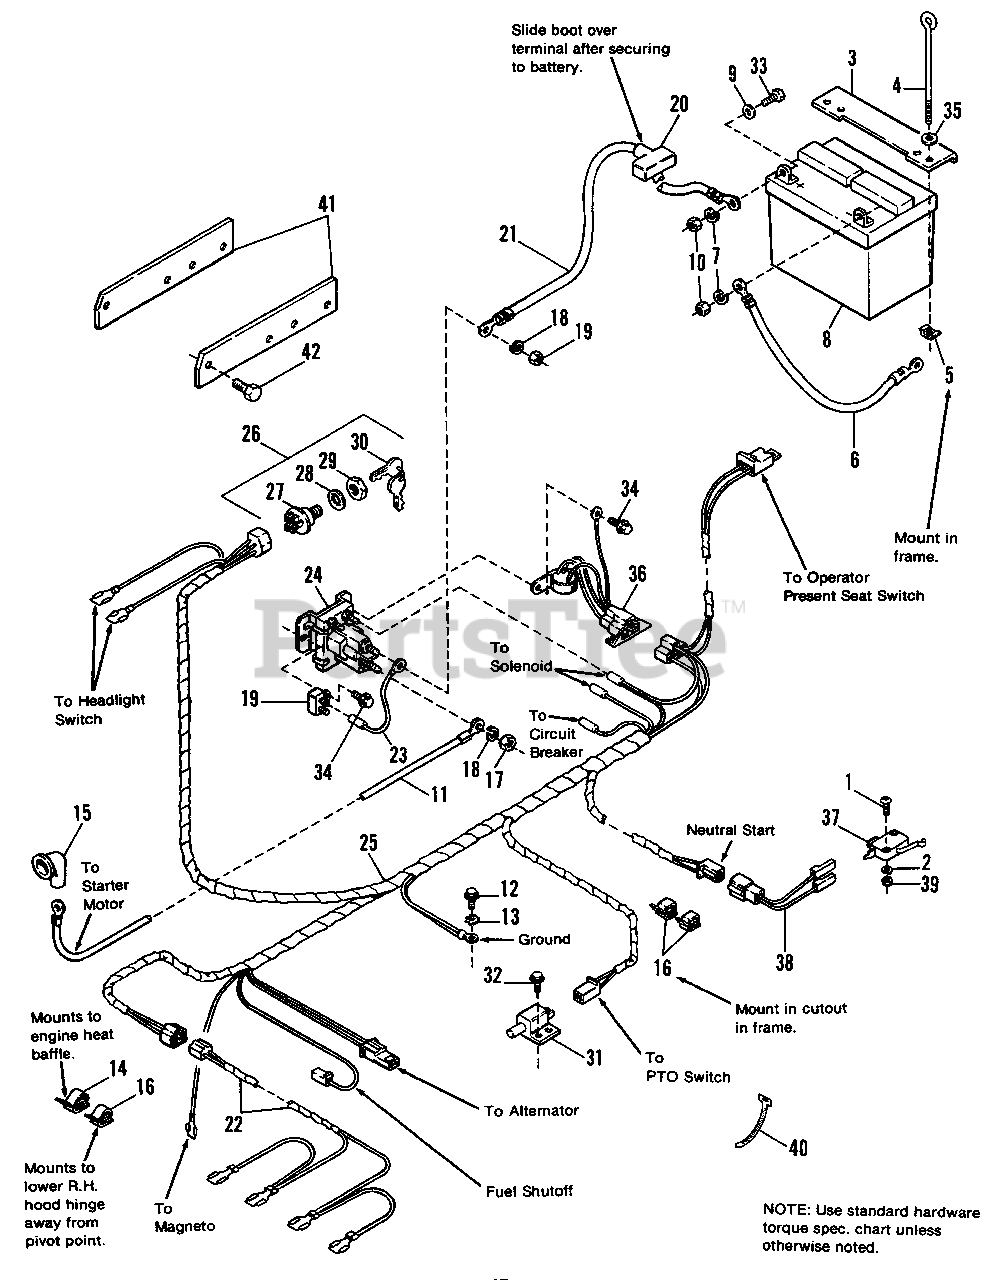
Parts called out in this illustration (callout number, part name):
1	SCREW, Phillips, #5-40 x 3/4
2	LOCKWASHERS, #5
3	HOLD DOWN, Battery
4	HOLD DOWN, Battery, Thrd.
5	NUT, Retainer, 1/4-20
7	LOCKWASHER, 1/4
8	BATTERY SERVICE KlT, 39 Amp (includes decal)
9	WASHER, Plain
10	NUT, Hex, Full, 1/4-20
11	CABLE (Solenoid to Starter)
12	SCREW, Taptite, 1/4-20 x 3/8 Zinc Pltd.
13	LOCKWASHER, Ext. Tooth
14	CLIP, Wire
15	COVER, Terminal
16	CLIP, Speed
17	NUT, Hex, Full, 5/16-18
18	LOCKWASHER, 5/16
19	BREAKER, Circuit
20	BOOT, Insulator
21	SCREW, Taptite, 5/16-18 x 3/8
22	WIRE ASSY., Headlights
24	SOLENOID
25	HARNESS, Wiring (1691431, 1691668)
26	SWITCH, Ignition (Incl. Ref. Nos. 29 & 30)
28	LOCKWASHER, Internal, 5/8
29	NUT, Hex, 5/8-32
31	SWITCH, P.T.O.
32	SCREW, Taptite, #10-24 x 1/2
33	CAPSCREW, 1/4-20 x 3/4
34	SCREW, Taptite, 1/4-20 x 5/8
35	WASHER, 1/4
36	MODULE-DSI, Interlock
37	SWITCH, Transmission Interlock
38	ADAPTOR, Wire
39	NUT, Hex, #5-40
41	BRACE, Shift Panel
